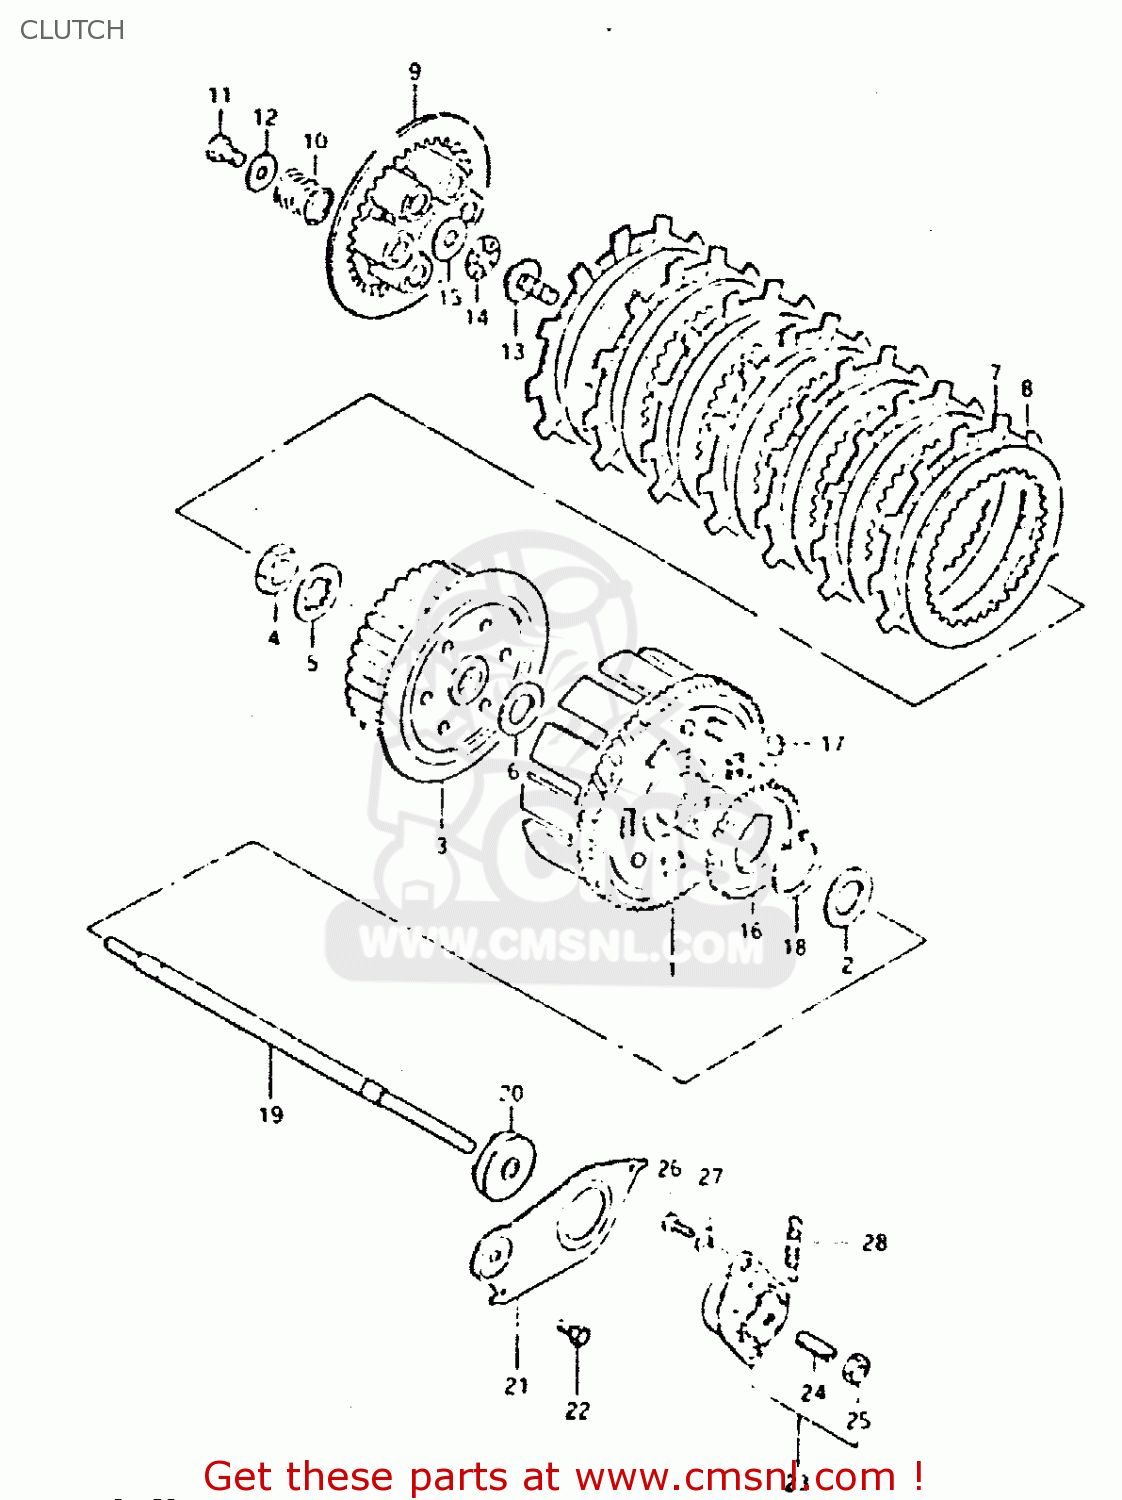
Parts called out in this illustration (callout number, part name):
1	GEAR ASSEMBLY,PRIMARY DRIVE
2	WASHER
3	HUB,CLUTCH SLEEVE
4	NUT (20MM)
5	WASHER,LOCK
6	WASHER(20X44X3)
7	PLATE,CLUTCH DRIVE (MCA)
8	PLATE, DRIVEN
9	DISC,CLUTCH PRESSURE
10	SPRING
11	BOLT, UPPER
12	WASHER
13	PIECE,CLUTCH PUSH
14	BEARING(15X28X2)
15	WASHER
16	GEAR,OIL PUMP DRIVE
17	PIN(6X6)
18	CIRCLIP
19	ROD,CLUTCH PUSH
20	SEAL,OIL(6X34X10)
21	PLATE,CLUTCH PUSH ROD
22	BOLT
23	SCREW ASSEMBLY,CLUTCH RELEASE
24	SCREW
25	NUT 6MM
26	SCREW
27	WASHER
28	SPRING
